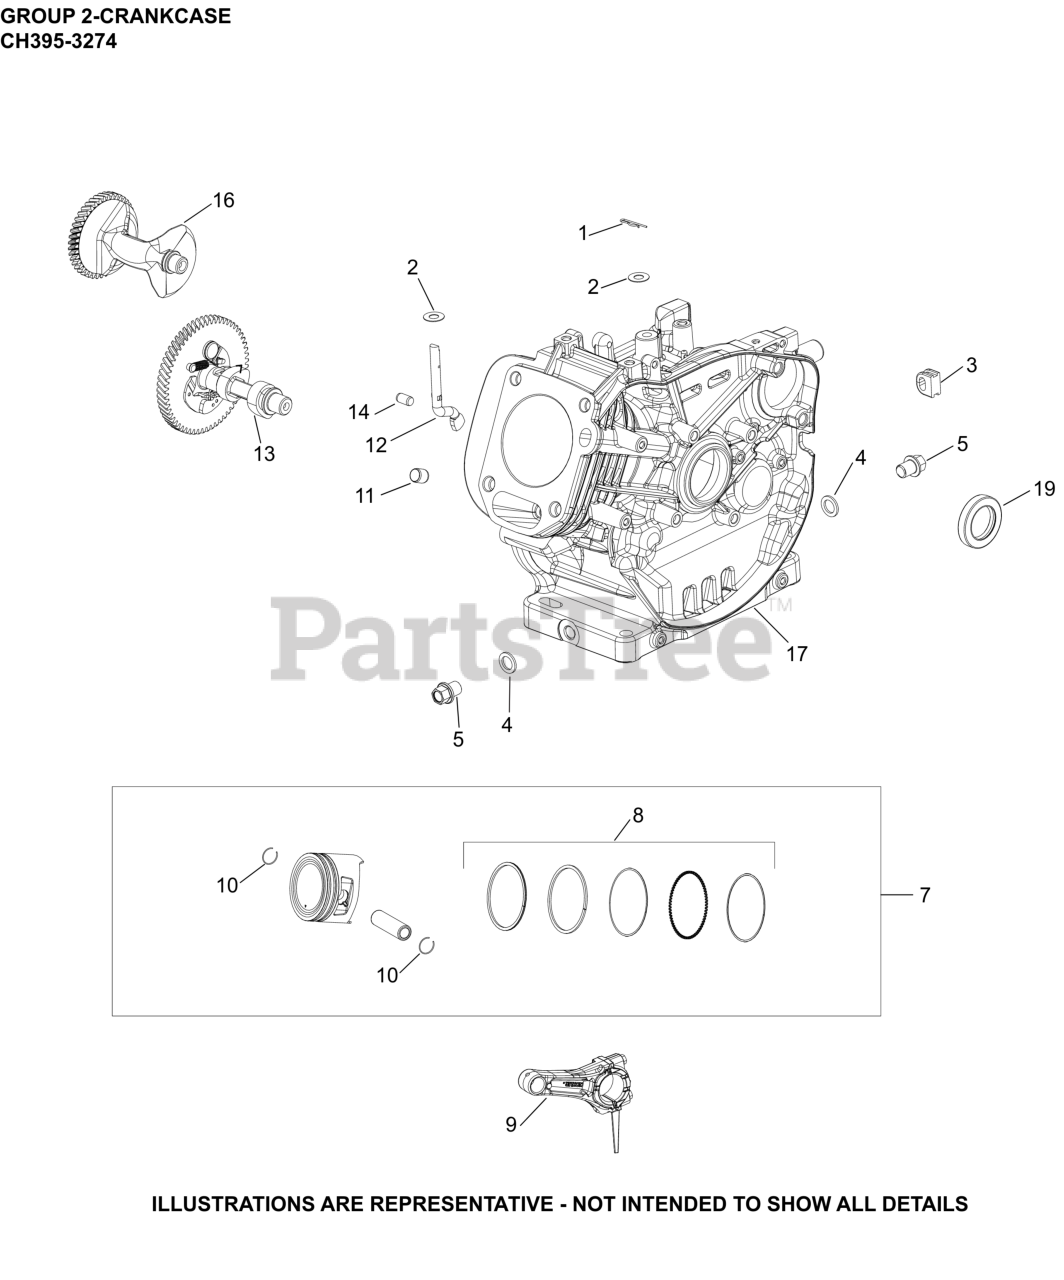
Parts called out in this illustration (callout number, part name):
1	CLIP, GOVERNOR SHAFT
2	WASHER, FLAT
3	GROMMET, CRANKCASE
4	WASHER, DRAIN PLUG
5	KIT, DRAIN PLUG
7	KIT, PISTON AND RINGS
8	RING SET- USE 17 874 06-S
8	RING, SET PISTION (std)
9	ROD, CONNECTING ASSEMBLY
10	RETAINER, PISTON PIN
11	PIN, DOWEL CYLINDER HEAD
12	SHAFT, GOVERNOR CROSS
13	CAMSHAFT ASSEMBLY
14	PIN, DOWEL
16	SHAFT, BALANCE
17	CRANKCASE
19	SEAL, RADIAL SHAFT
